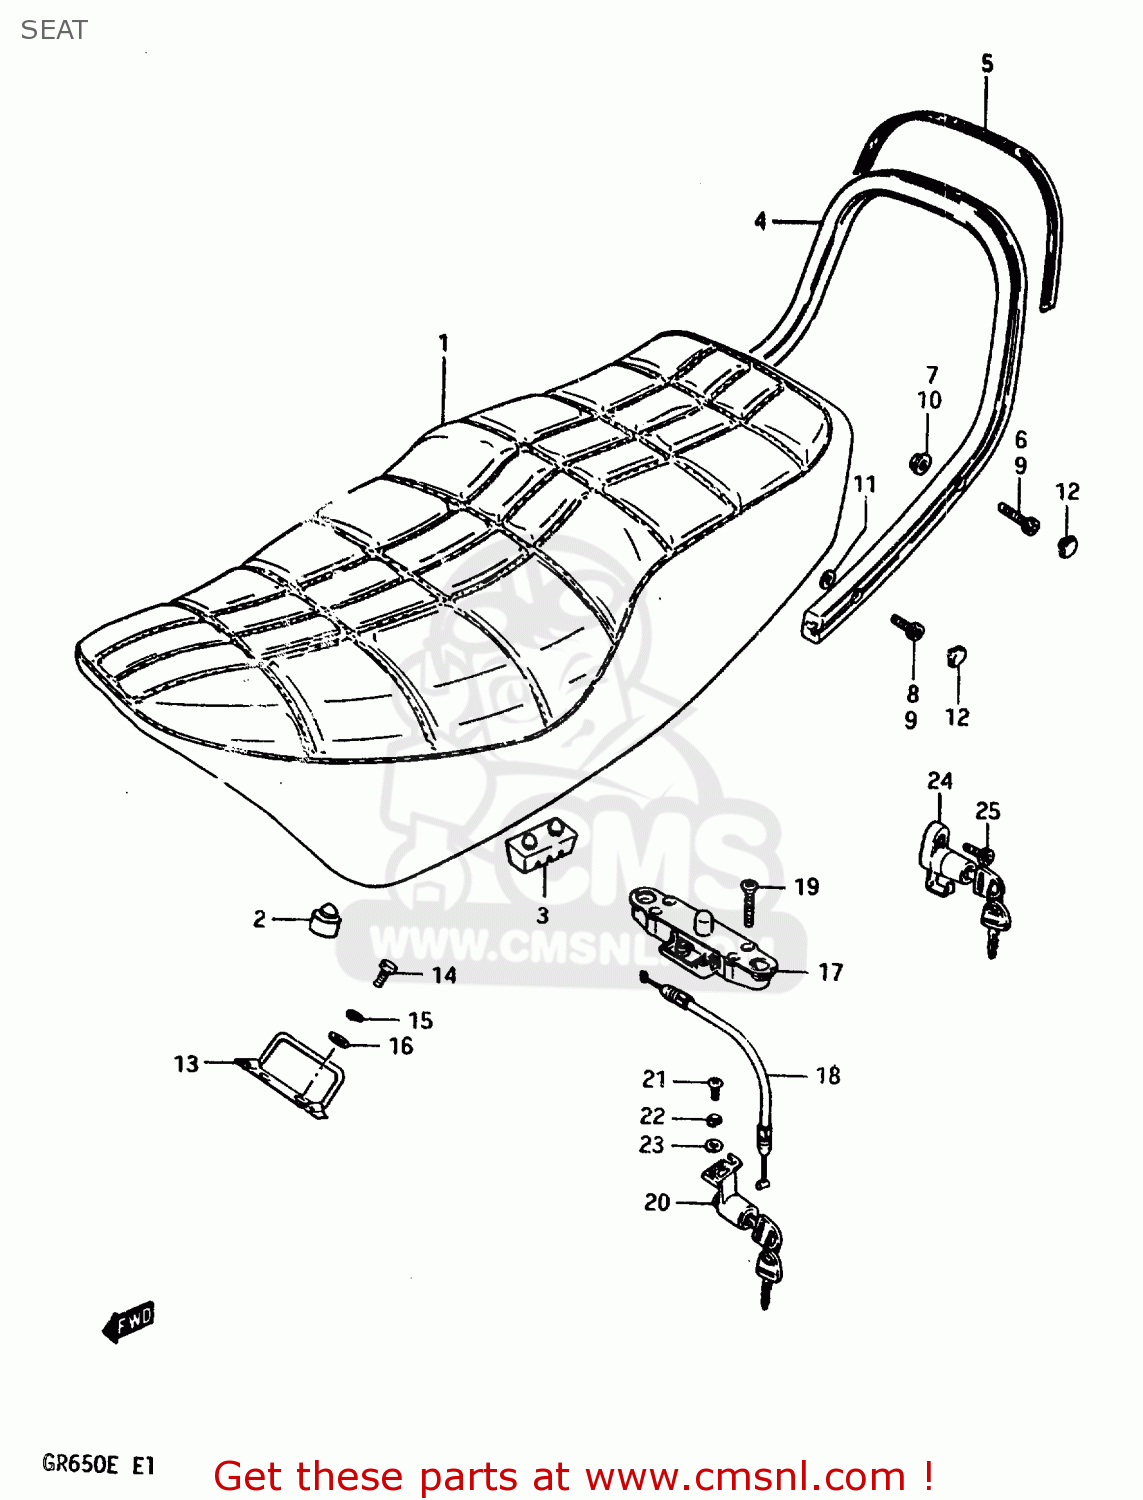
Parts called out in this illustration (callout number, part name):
1	SEAT ASSEMBLY
2	CUSHION
3	CUSHION
4	HANDLE,PILLION RIDER
5	RUBBER,PILLION RIDER HANDLE
6	BOLT
7	NUT 8MM
8	BOLT
9	BOLT
10	NUT
11	WASHER
12	CAP(OD:14.5)
13	PLATE,SEAT HOOK,FRONT
14	BOLT,M6X1X20
15	WASHER,LOCK
16	WASHER, LOWER
17	LOCK ASSEMBLY,SEAT STRIKER
18	CABLE,SEAT LOCK
19	SCREW
20	LOCK ASSEMBLY,SEAT
21	SCREW
22	WASHER,LOCK
23	WASHER,5MM
24	LOCK SET
25	BOLT
